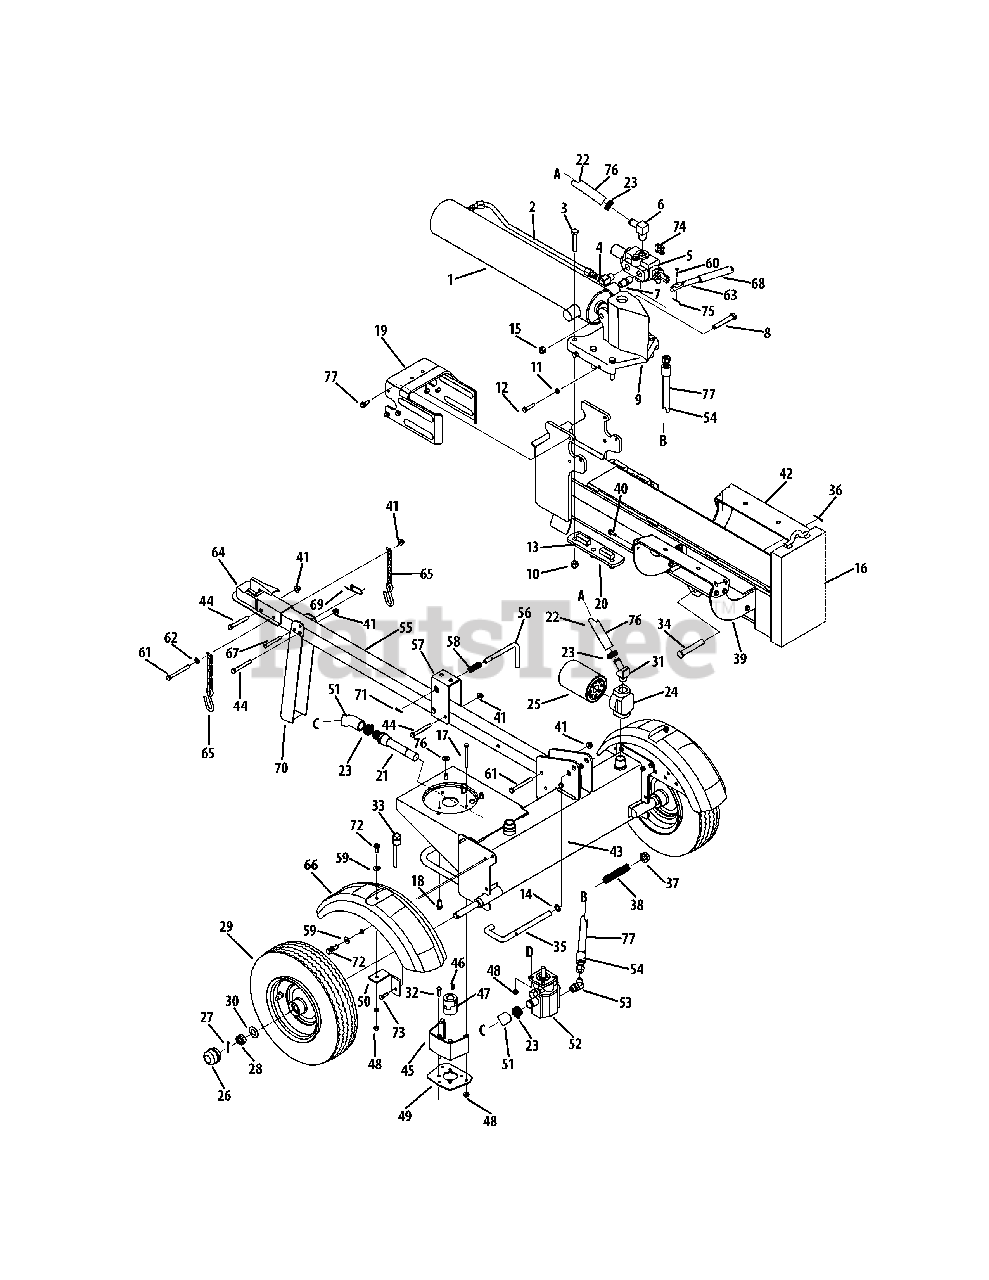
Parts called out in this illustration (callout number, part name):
1	Hydraulic Cylinder
2	Hydraulic Tube
3	Hex Cap Screw, 1/2-20 x 2.75
4	90 Degree Solid Adapter
5	Control Valve
6	Return Elbow
7	Nipple Pipe, 1/2-14
8	Hex Cap Screw, 1/2-13 x 3.25
9	Wedge Assembly
10	Hex Lock Nut, 1/2-20
11	Hex Jam Nut, 3/8-24
12	Hex Cap Screw, 3/8-24 x 1.5
14	Flat Washer, .635 x.93 x.06
15	Hex Lock Nut, 1/2-13
16	Beam Assembly
17	Hex Screw, 5/16-18 x 3.25
18	Hex Washer Screw, 3/8-16 x 1.250
19	Dislodger Bracket
20	Back Plate
21	Inlet Filter
22	Return Hose, 3/4 x 44
23	Hose Clamp, 5/8"
24	Filter Housing
25	Oil Filter
26	Hub Cap
27	Cotter Pin
28	Slotted Nut, 3/4-16
29	Wheel Assembly
30	Flat Washer, .760 x.500
31	Adapter, 3/4-14
32	Hex Screw, 5/16-18 x 1.00
33	Vented Dipstick
34	Clevis Pin
35	Lock Rod
36	Cotter Pin
37	Push Cap
38	Compression Spring
39	Log Tray Bracket
40	Hex Washer Screw, 5/16-18 x .750
41	Flange Lock Nut, 3/8-16
43	Frame Assembly
44	Hex Bolt, 3/8-16 x 3"
45	Coupling Shield
46	Square Key, 3/16" x.75
47	Coupling, .500, Engine Side
47	Coupling, .875, Pump Side
48	Flange Lock Nut, 5/16-18
49	Rear Coupling Support Bracket
50	Fender Mounting Bracket
52	Gear Pump
53	45 Degree Elbow Fitting
54	High Pressure Hydraulic Hose
55	Tongue Assembly
56	Latch Rod
58	Compression Spring
59	Flat Washer
60	Clevis Pin
61	Hex Cap Screw, 3/8-16 x 3.50
62	Flat Washer, .375 x.738 x.063
63	Hydraulic Valve Control
64	Hitch Coupling Assembly
66	Fender
67	Clevis Pin
69	Spring Pin
70	Jack Stand
71	Spiral Pin
72	TT Screw, 5/16-18 x 0.875"
73	TT Screw, 5/16-18 x 1.00
74	Valve Handle Link
75	Cotter Pin
76	Flat Washer, .407 x .812 x .135
77	Hex Washer Screw, 5/16-18 x .750
